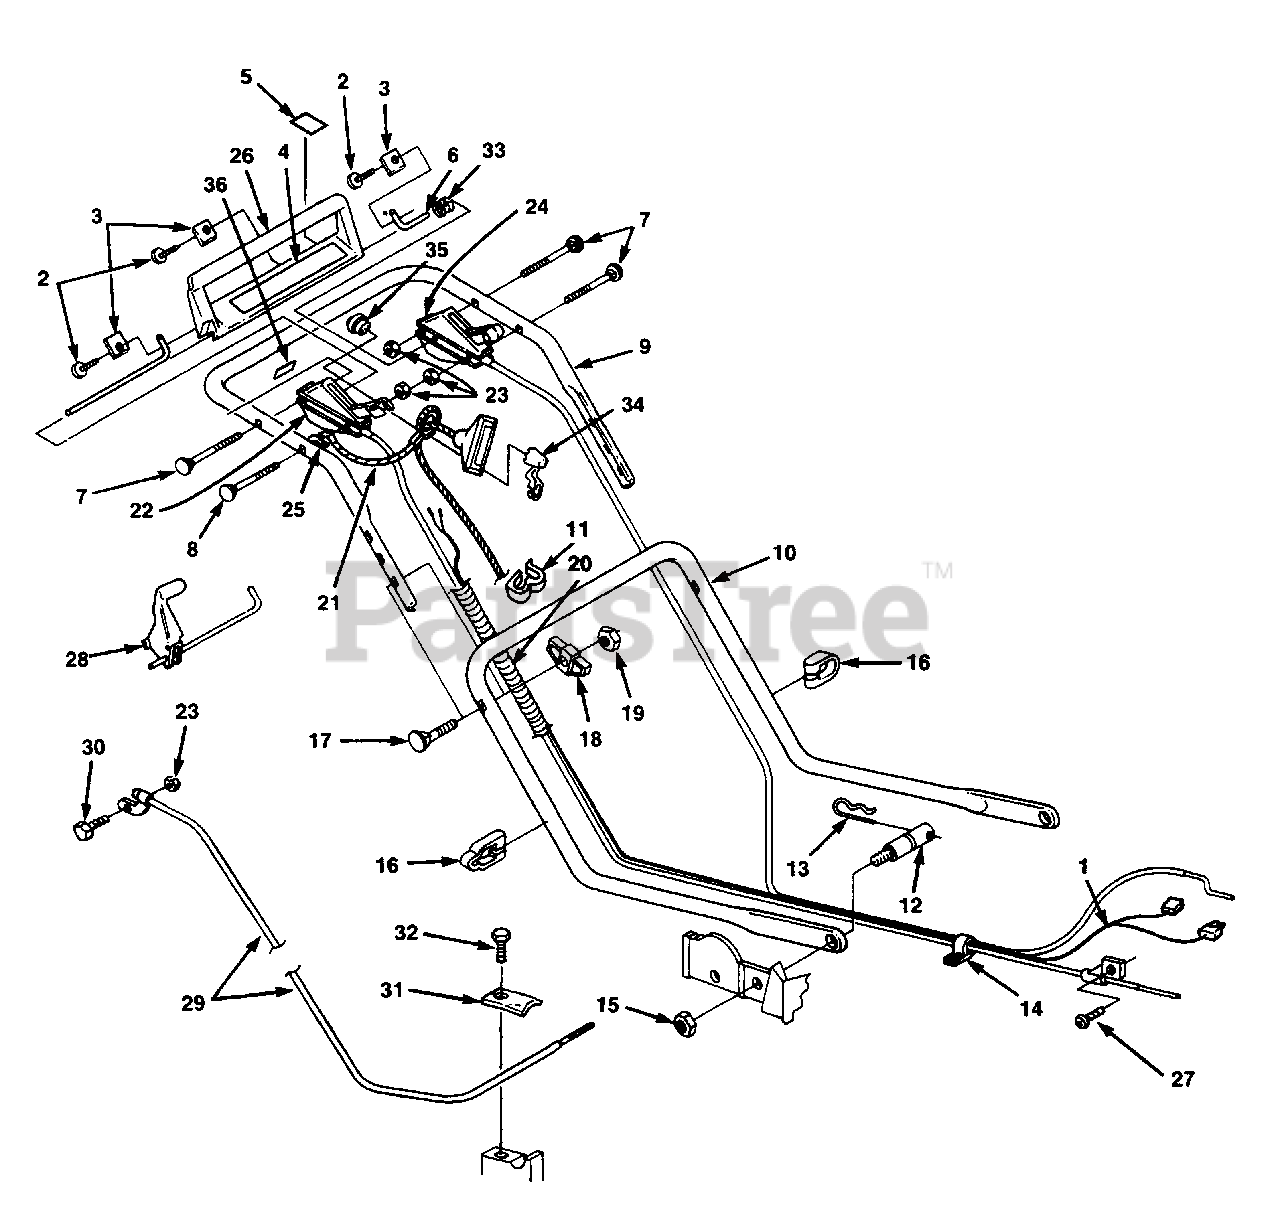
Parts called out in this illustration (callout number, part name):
1	WIRING HARNESS
2	SCREW, Rd. Hd., 1/4-10 x 5/8
3	CLAMP, Pivot Shaft
4	DECAL, Brake Bail
5	DECAL, Blade Rotation
6	SHAFT, Pivot (Short)
7	BOLT, Sq. Neck
8	BOLT, Sq. Neck
9	HANDLE, Upper
10	HANDLE, Lower
11	CLIP, Cover
12	STUD, Handle Mtg.
13	PIN, Cotter Hair
15	NUT, Hex Flange, 5/16-18
16	CLAMP, Cable (Double)
17	BOLT, Sq. Neck
18	KNOB, Handle
19	NUT, Hex Locking, 5/16-18
20	COVER, Control Cable
21	ROPE, Restraint
22	CONTROL ASSEMBLY
23	NUT, Hex Locking, 1/4-20
24	CONTROL, Throttle
25	WASHER, Curved
26	BAIL, Brake Control
27	SCREW, Hex Hd., 10-32 x 3/8
28	TRACTION LEVER
29	CABLE, Traction
30	SCREW, Hex Hd., 1/4-20 x 1-1/2
32	SCREW, Hex Hd., 1/4-20 x 5/8
33	SPRING, Compression
34	HOUSING, Switch
35	SWITCH
36	DECAL, Switch
